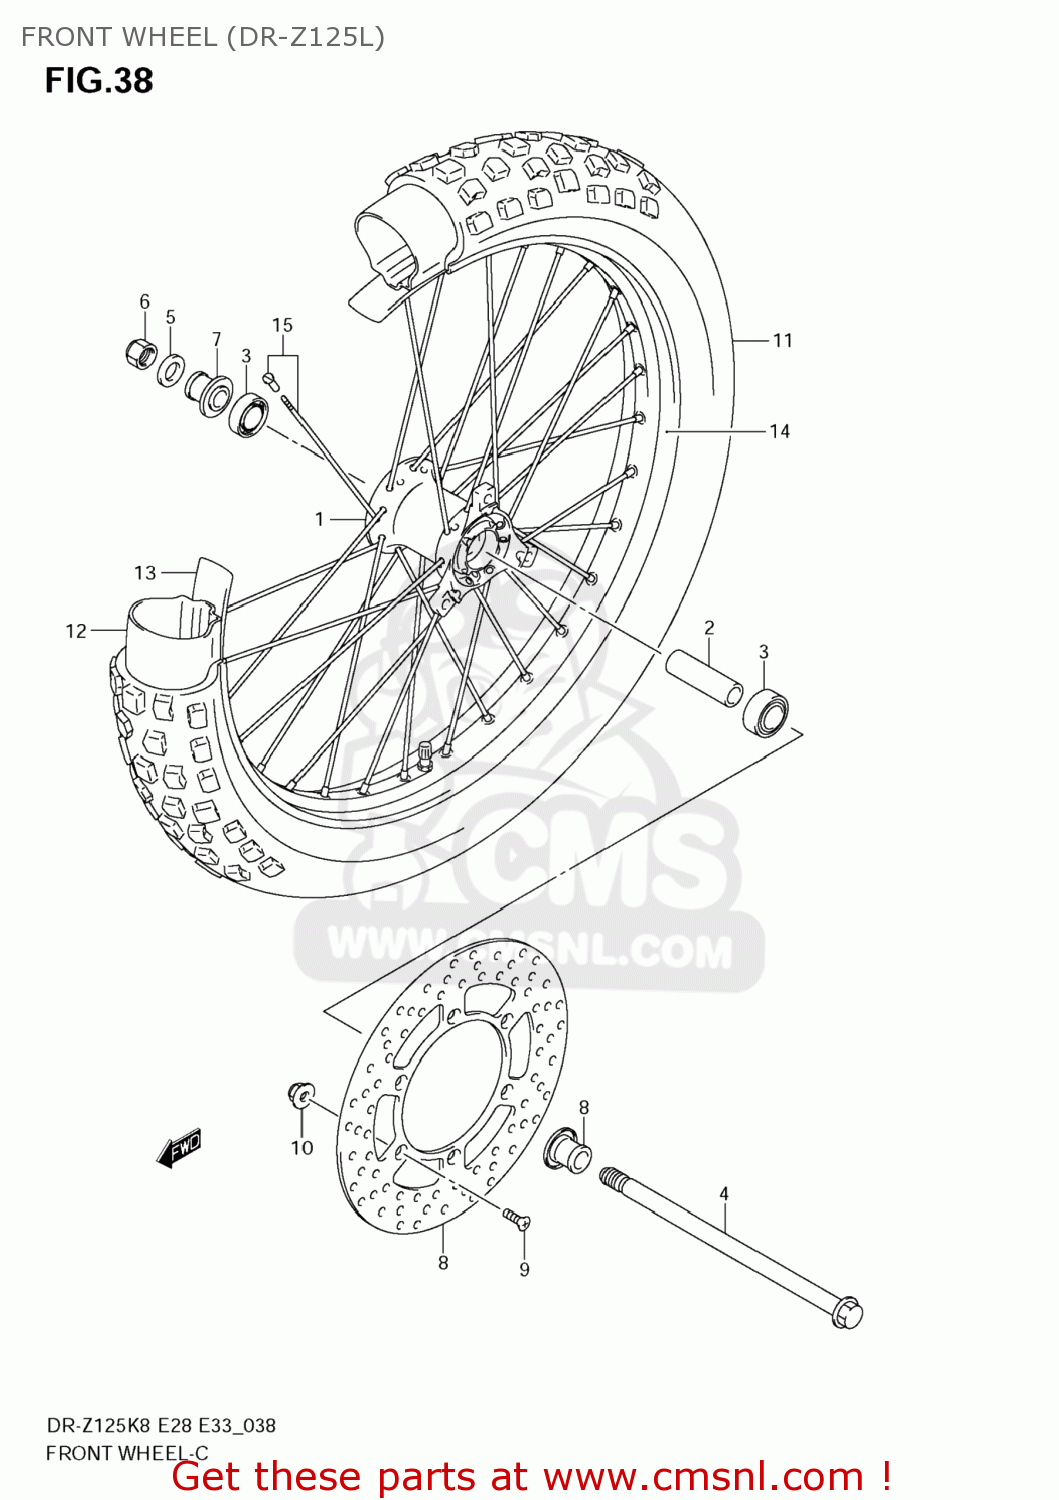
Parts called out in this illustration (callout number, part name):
1	HUB,FR WHEEL
2	SPACER,FR HUB BEARING
3	BEARING (12X32X10)
4	AXLE,FR
5	WASHER(12.5X24X3.2)
6	NUT
7	SPACER,FR AXLE
8	DISC,FR BRAKE
9	SCREW(6X22)
10	NUT
11	TIRE,FR
12	TUBE ASSY,WHEEL INNER
13	PROTECTOR,WHL INR TUBE
14	RIM,FR WHEEL(19X1.40)
15	SPOKE SET,FR WHEEL
